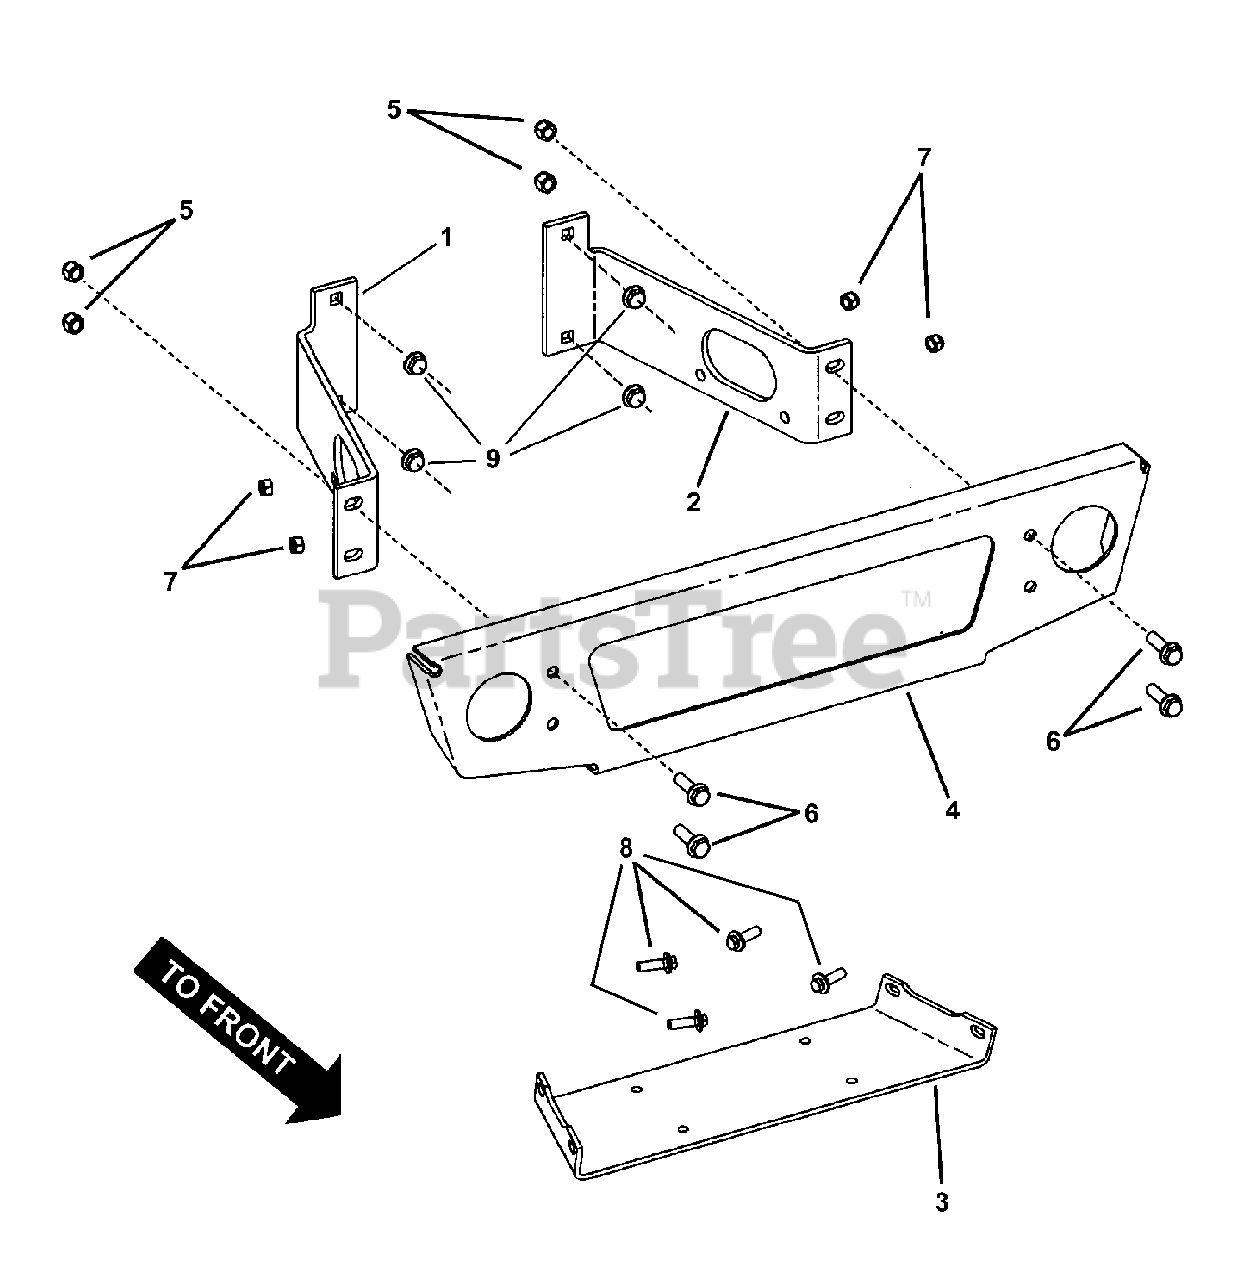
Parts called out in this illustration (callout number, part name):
1	SUPPORT, Bumper LH
2	SUPPORT, Bumper RH
3	PLATE, Winch
4	BUMPER
5	NUT, Hex Nyloc, 3/8-16
6	BOLT, Hex Flange Lock, 3/8-16 x 1-1/4
7	NUT, Hex Nyloc, 5/16-18
8	BOLT, Hex Flange Lock, 5/16-18 x 1
9	NUT, Hex Flange Lock, 3/8-16
